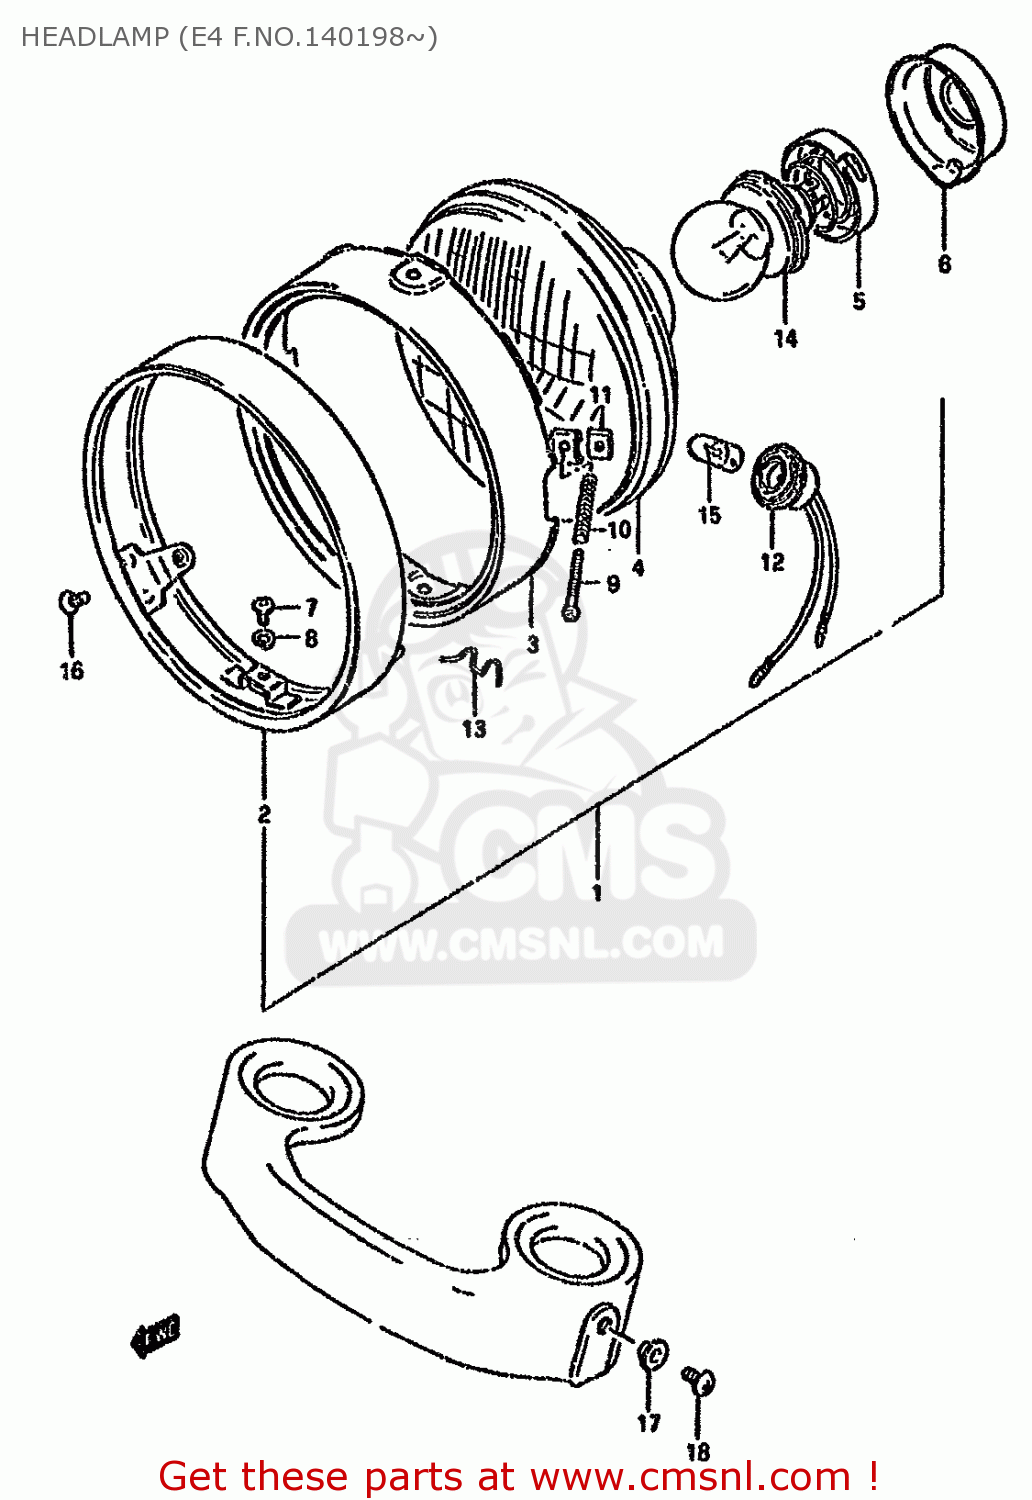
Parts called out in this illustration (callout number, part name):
1	HEADLAMP ASSY
2	RIM
3	RETAINER
4	LAMP UNIT
5	SETTER,BULB
6	COVER,HEADLAMP BULB
7	SCREW
8	LOCK WASHER
9	SCREW
10	SPRING
11	NUT
12	SOCKET
13	SPRING
14	BULB(12V45/40W)
15	BULB(12V4W)
16	SCREW(5X12)
17	WASHER
18	SCREW
